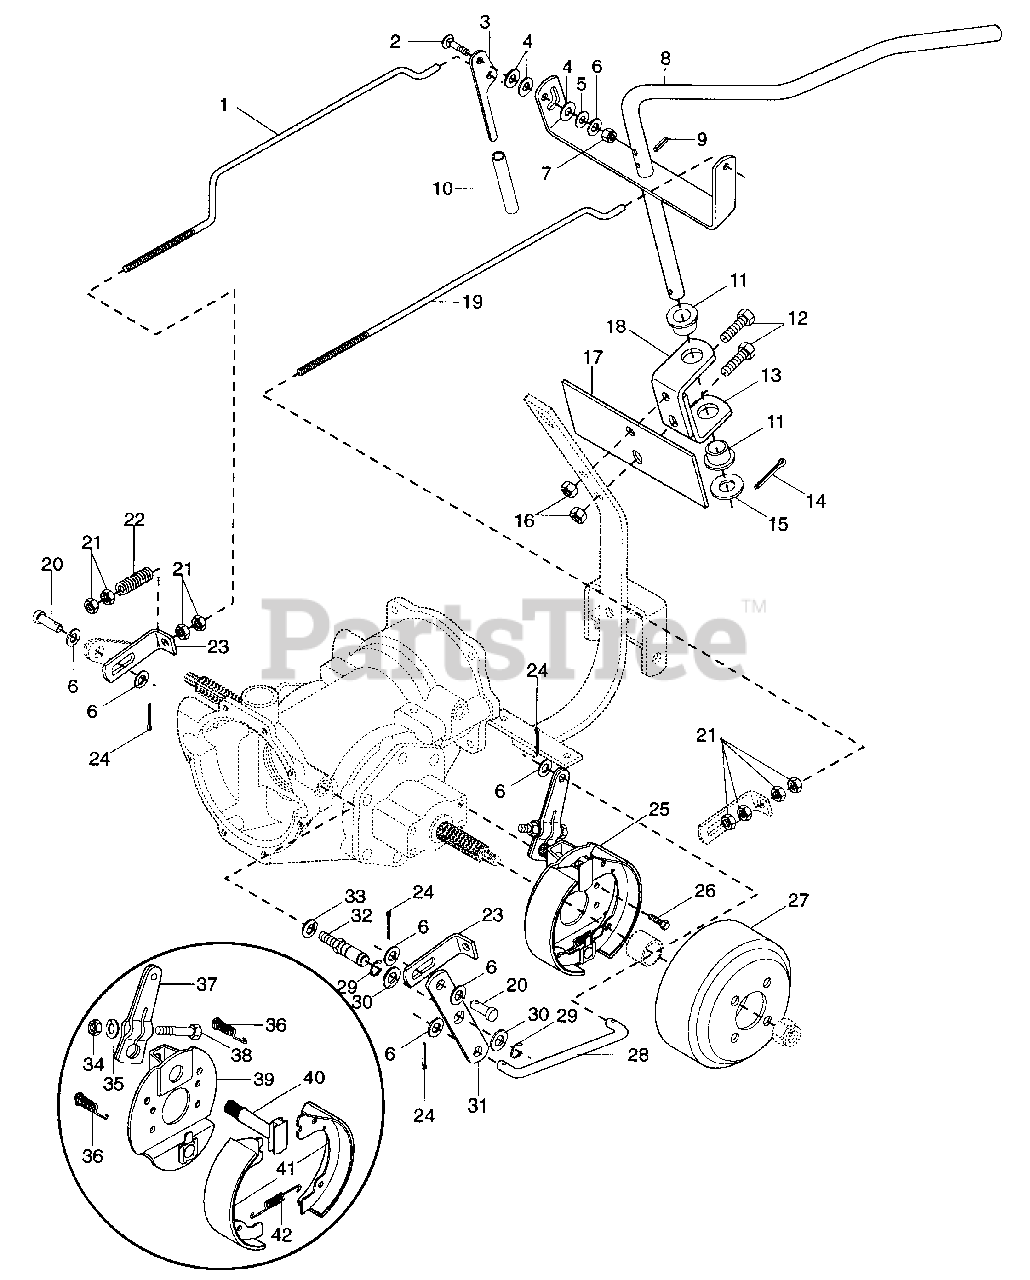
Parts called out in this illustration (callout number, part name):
1	Rod, Brake Right Hand(16 HP)
2	Bolt-Round Head Square Neck .38-16 x 1.50
3	Handle, Parking Brake
4	Washer-Flat-Nylon .375 x .75 x .060
5	Washer-Rubber .375 x .75 x .125
6	Washer-Flat-Steel .406 x .812 x .065
7	Nut-Locking-Nylon .375 - 16
8	Weldment, Brake Handle
9	Pin-Roll .313 x 2.00
10	Grip, Brake Handle
11	Bushing-Flange 1.082 x 1.385 x .870 x 1.750
12	Bolt-Hex .50-13 x 2.00 Grade 5
13	Bracket, Brake Handle
14	Pin-Cotter .188 x 1.50
15	Washer-Flat-Steel 1.120 x 1.500 x .092
16	Nut-Locking-Nylon .50-13
17	Plate, Instruction
18	Bracket, Brake Handle
19	Rod, Brake
20	Pin, Clevis
21	Nut-Jam .375-16
22	Spring-Compression .105 x .61 x 2.50
23	Bracket, Adjustment
24	Pin-Cotter .09 x .75
25	Brake. 7 x 1 3/4 Mechanical
26	Bolt-Hex .380 - 16 x .875
27	Drum, 7 x 1 3/4
28	Rod, Brake Link
29	Ring-Retaining-External .625 x .042
30	Washer-Flat-Steel .656 x 1.312 x .095
31	Plate, Pivot
32	Stud, Pivot
33	Washer-Lock .50
34	Nut-Hex .312-24
35	Washer-Lock .313 x .078
36	Spring, Shoe Ret Box
37	Arm, Cam Lever
38	Bolt-Hex .31-24 x 1.75
39	Bushing-Sleeve .277 x .375 x 1.37
40	Cam, Brake
41	Kit, Brake Shoe
42	Spring, Shoe Return
